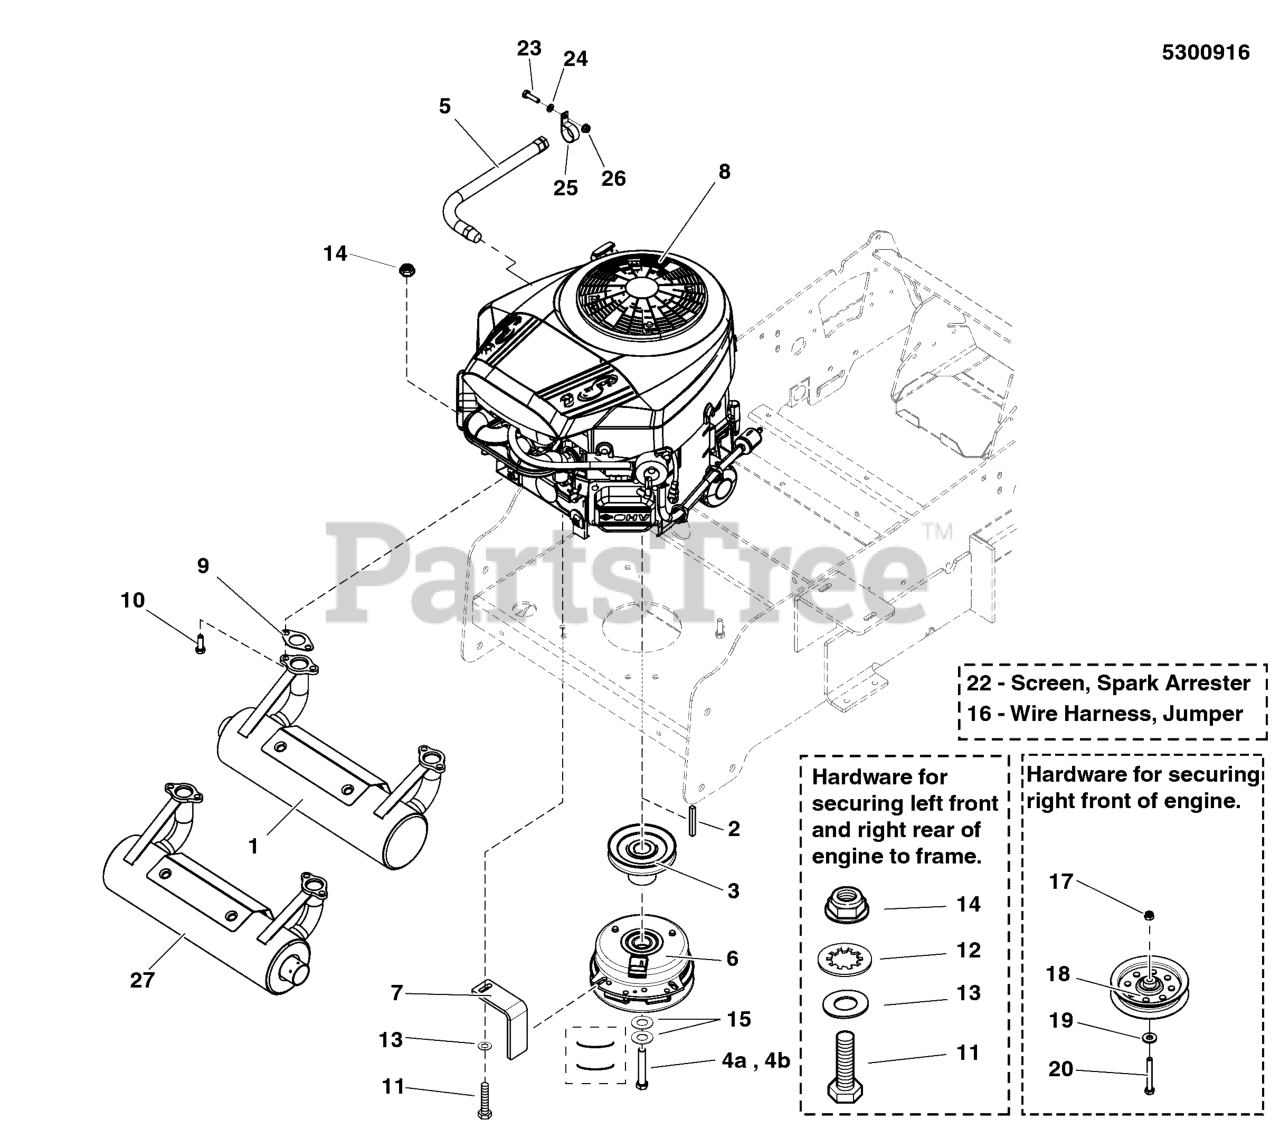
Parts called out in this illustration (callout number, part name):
1	MUFFLER, B&S-ELS
2	KEY, 1/4 SQ X 1
3	PULLEY, PUMP DRIVE, 4.857 OB X 1" BORE
5	HOSE, OIL DRAIN
6	CLUTCH, # 5219-34A, ELECTRIC, IS500Z
7	ANCHOR, CLUTCH - BLK
8	ENGINE, B&S
9	GASKET, Exhaust
11	BOLT, 5/16-24 X 1-3/4, GD8
12	WASHER, 5/16" INT. TOOTH LOCK
13	WASHER, 5/16" SAE
14	NUT, 5/16-24, NYLOCK FLANGE, GD8, CZ
15	BELLEVILLE WASHER 1.1875 X .442 X .089
17	SEE PUMP DRIVE GROUP
18	SEE PUMP DRIVE GROUP
19	SEE PUMP DRIVE GROUP
20	SEE PUMP DRIVE GROUP
23	BOLT, 1/4-20 X 1" GD5 CZ
24	WASHER, 1/4 SAE
25	CLAMP, VINYL INSULATED
26	NUT, 1/4-20 HEX NYLOCK FLANGE
27	MUFFLER, RIGHT OUTLET ASSY
